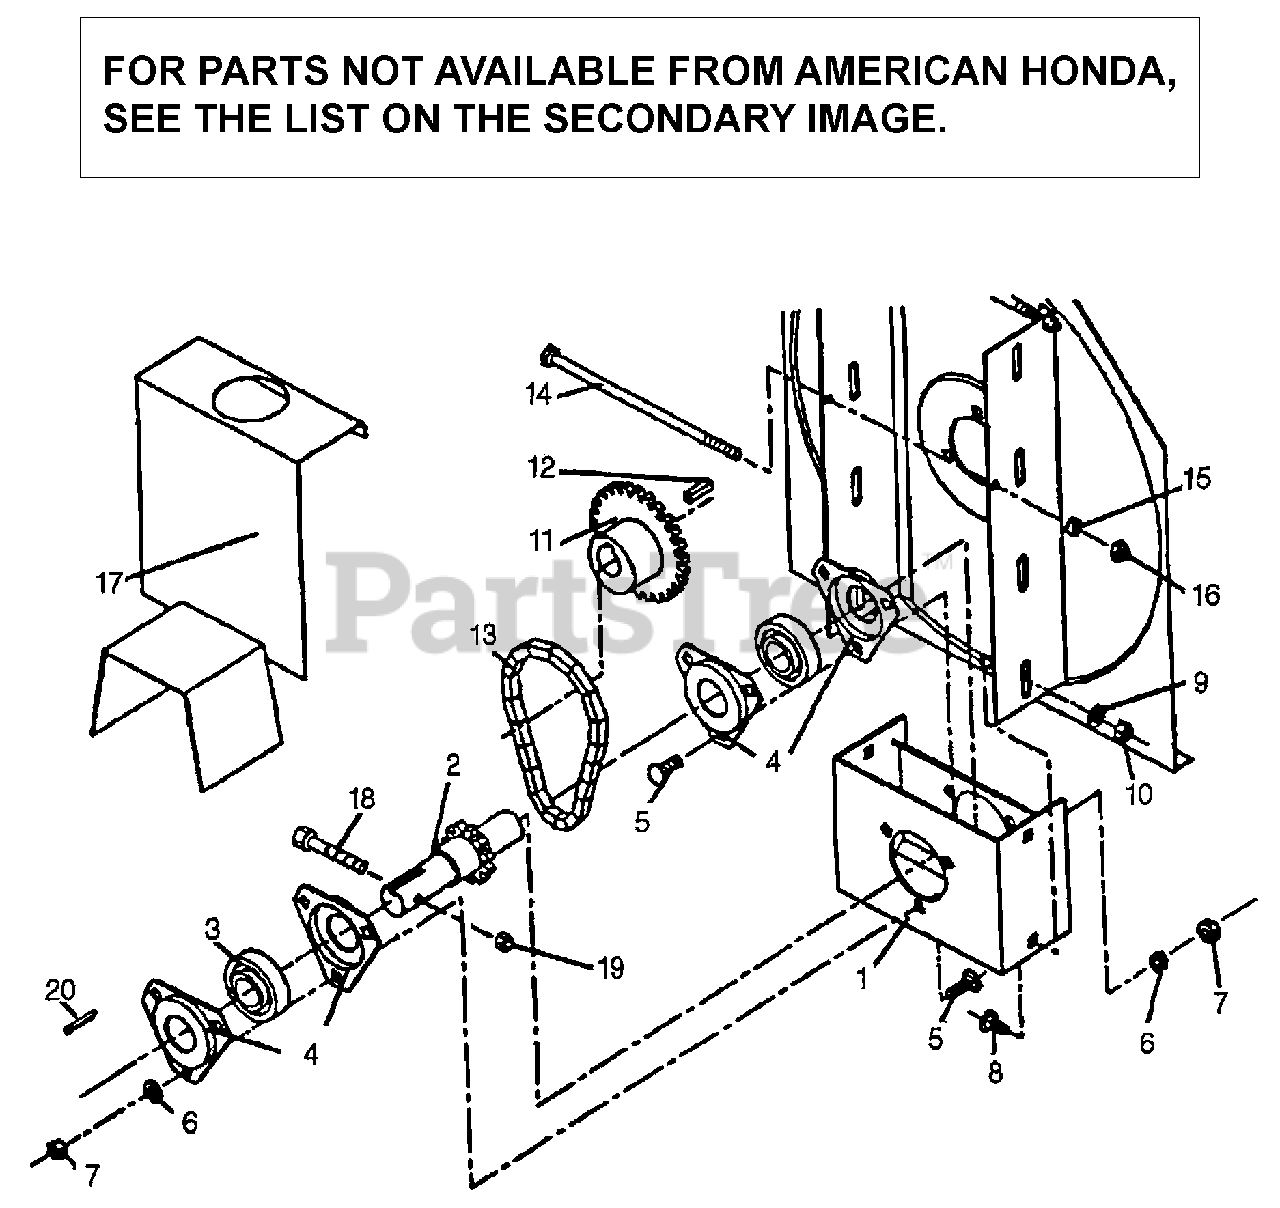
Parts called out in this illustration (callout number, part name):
1	BOX, REDUCTION
2	DRIVESHAFT, W/SPROCKET
3	BEARING, W/LOCKING SCREW
4	FLANGE, BEARING
11	SPROCKET (H40B32)
12	KEY (1/4X1/4X1") (LG.)
13	CHAIN (#40X37L)
17	FLANGE, BEARING
20	KEY (1/4X1/4X1 1/4")
